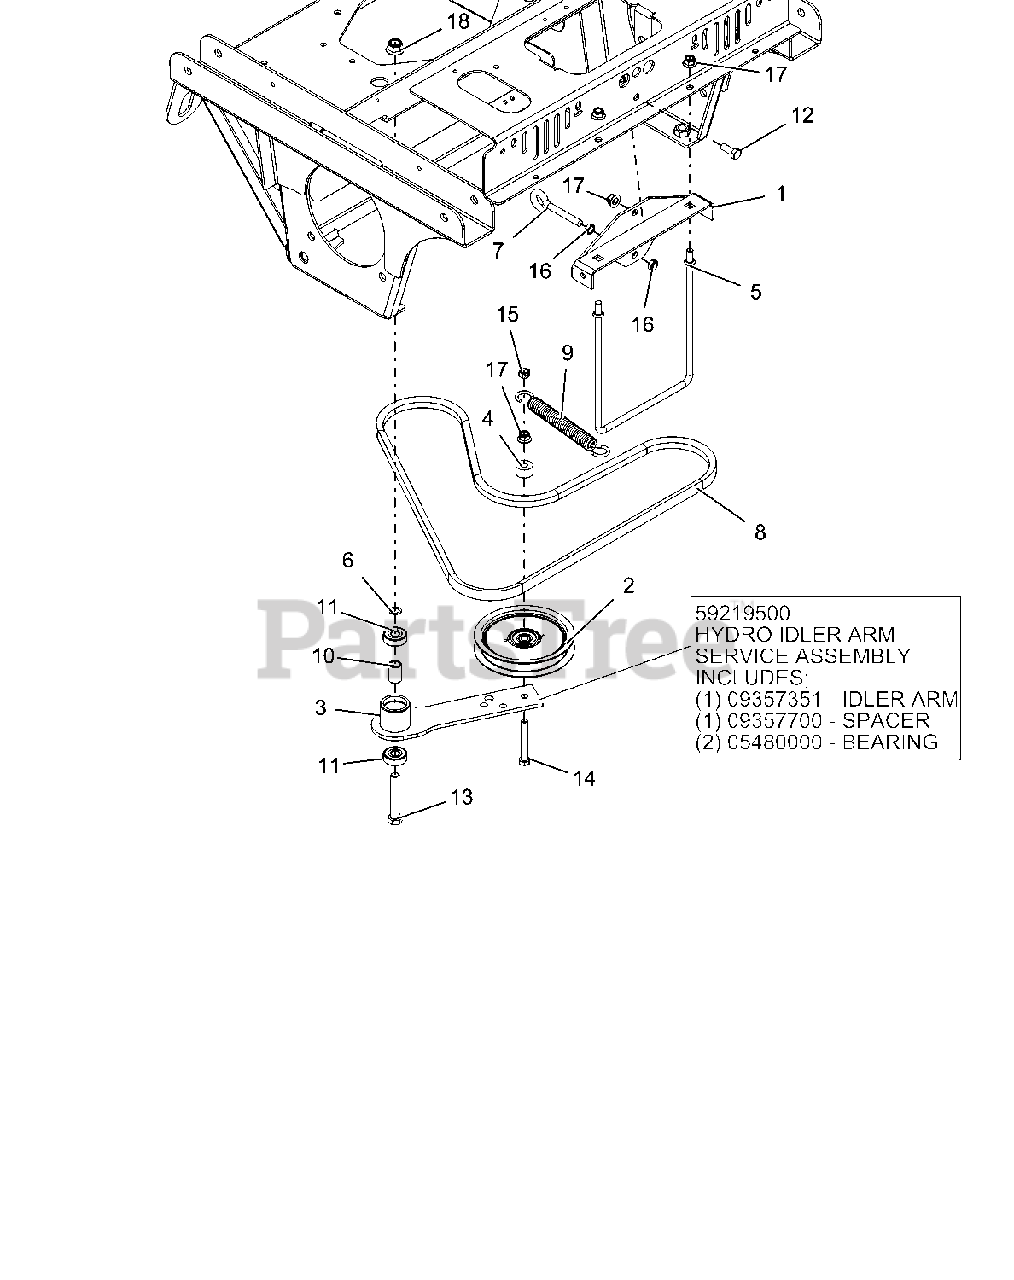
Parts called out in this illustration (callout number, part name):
1	SPRING ANCHOR BRKT WMT - BLACK
2	IDLER, FLAT-5.00X.75
3	BRG-BALL .50X1.38X.438 SEALED
3	SPACER .510 X .75 X 1.1485
3	KIT, HYDRO IDLER ARM PT200/400
3	HYDRO DRIVE IDLER ARM WMT- BLK
4	SPACER .390X1.000X.562
5	ROD, BRAKE MTG
6	WASHER, .500X.750X.020 THRUST
7	BLT-EYE .375-16X2.50 YWZC
8	V-BELT, COGGED B-RAW EDGE
9	SPRING, EXTENSION
10	SPACER .510 X .75 X 1.1485
11	BRG-BALL .500X1.38X.437
12	@BLT-HEX .38-16X1.00 GR5 YWZC
13	@BLT-HEX .50-13X3.00 GR5 YWZC
14	@BLT-HEX .38-16X2.75 GR5 YWZC
15	@NUT-LK-CTR .38-16 YWZC
16	NUT-HEX-JAM .375-16 YWZC
17	@NUT-LK-NYL-FLG .38-16 YWZC
18	@NUT-LK-NYL-FLG .50-13 YWZC
